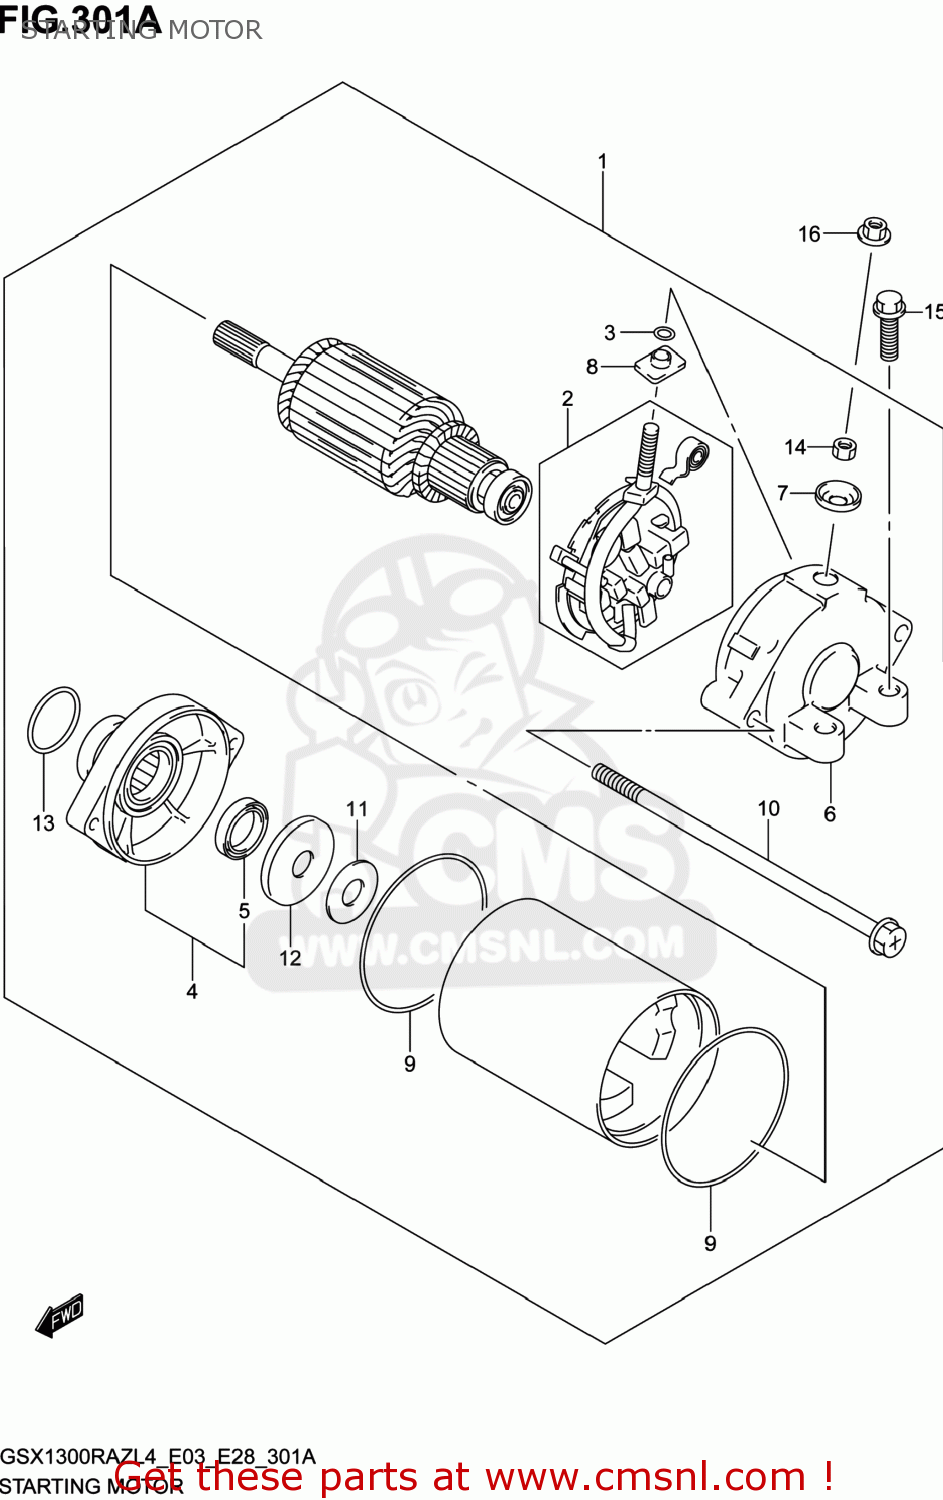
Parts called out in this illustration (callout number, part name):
1	MOTOR ASSY,STARTING
2	HOLDER SET,BRUSH
3	O RING
4	HOUSING ASSY,STARTER
5	SEAL,OIL
6	FRAME,STARTER END
7	BUSHING
8	BUSHING
9	O RING
10	BOLT
11	SHIM
12	WASHER
13	O RING(D:3,ID:24.5)
14	NUT
15	BOLT(6X25)
16	NUT
